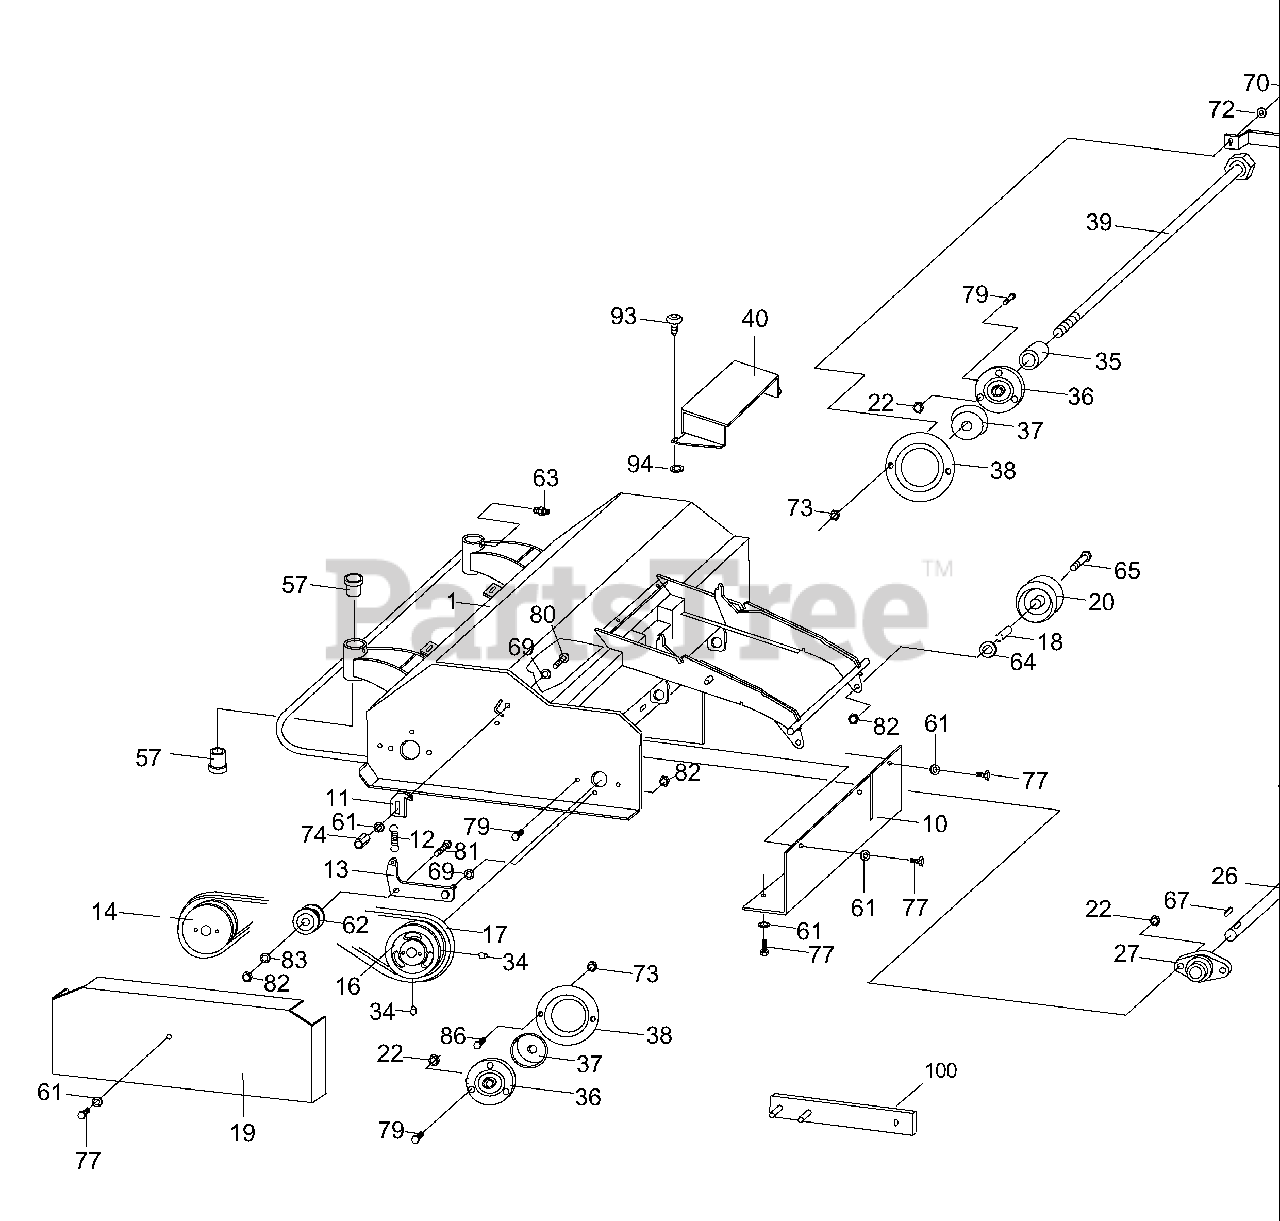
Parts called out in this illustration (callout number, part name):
14	Pulley SPA 144-1
17	V-Belt
18	Collar
19	Belt Guard
20	Support Wheel
21	Flail, Flail Mower
24	Gear Box, 1:1
25	Universal Joint
26	Drive Shaft
28	Pin, Spring
38	Guard Plate
39	Screw, Special
43	Guard, Shaft
51	Support Wheel
57	Bearing, Plastic
63	Nipple, Crease
80	Screw, Lock
91	Reinforcement strap
93	Screw, special
101	Shaft, Flail mower
